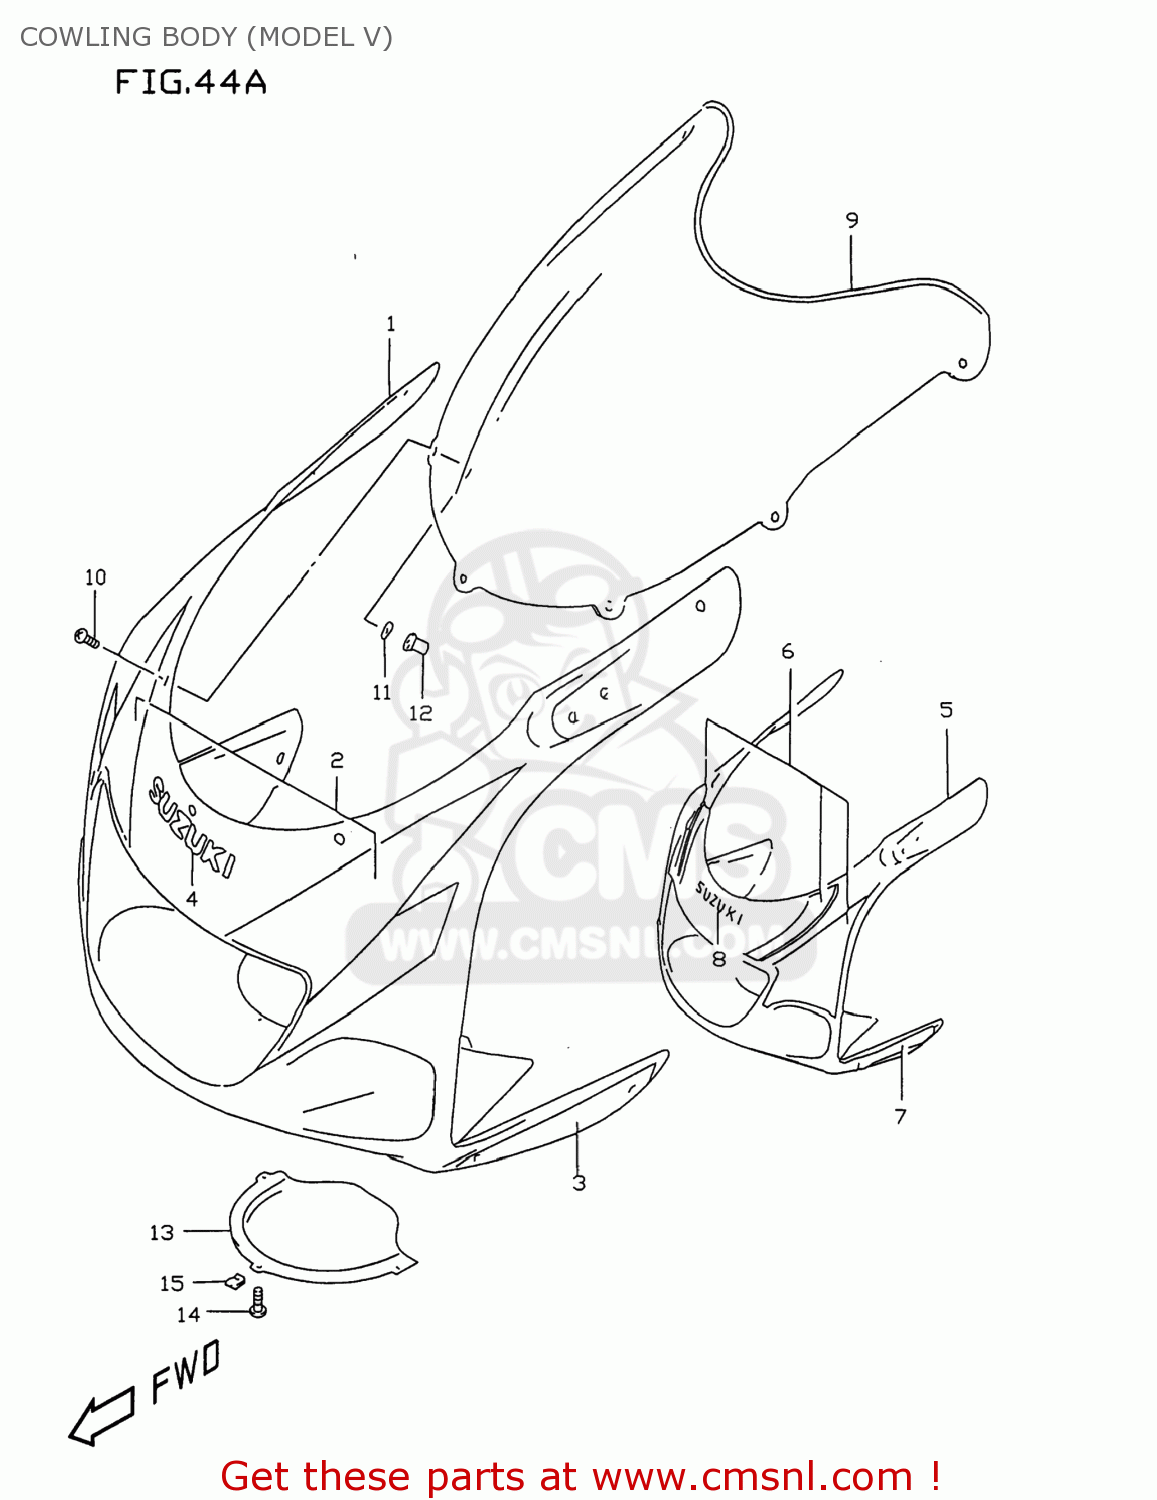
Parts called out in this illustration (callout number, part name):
1	COWLING ASSY,BODY
2	TAPE SET,COWL BODY FR
3	TAPE SET,COWLING BODY SIDE
4	EMBLEM,SUZUKI
5	COWLING ASSY,BODY
6	TAPE SET,COWL BODY FR
7	TAPE SET,COWLING BODY SIDE
8	EMBLEM,SUZUKI
9	WINDSCREEN
10	SCREW(5X14)
11	WASHER
12	NUT
13	LID,BODY COWLING,LOWER
14	SCREW
15	NUT
